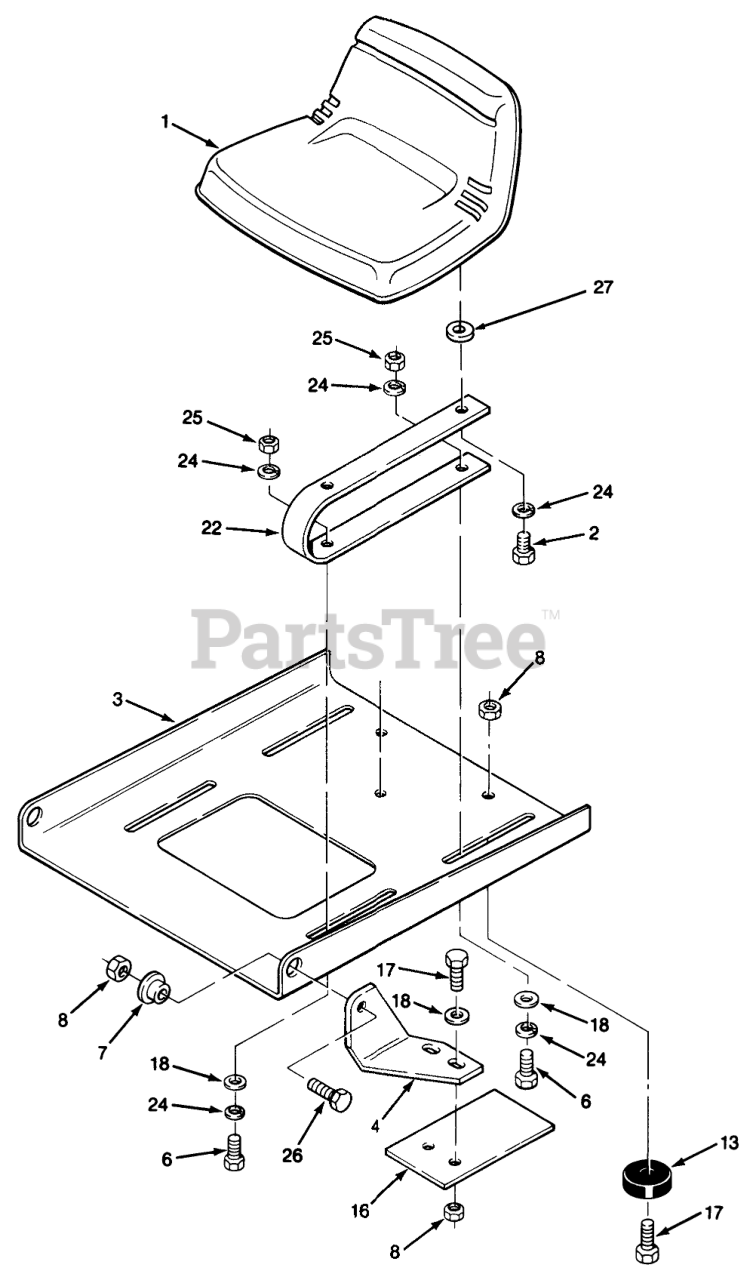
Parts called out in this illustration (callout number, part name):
1	SEAT V-410
2	SCREW-HH
3	PLATE-SEAT PIVOT B
4	BRACKET-PIVOT L.H B
6	SCREW-HH
7	BUSHING
8	NUT-LOCK, NI
13	BUMPER
16	PLATE R
17	SCREW-HH
18	WASHER-PLAIN
22	SPRING-SEAT B
24	WASHER-LOCK
25	NUT-HEX
26	SCREW-HH
27	SPACER-NYLON
